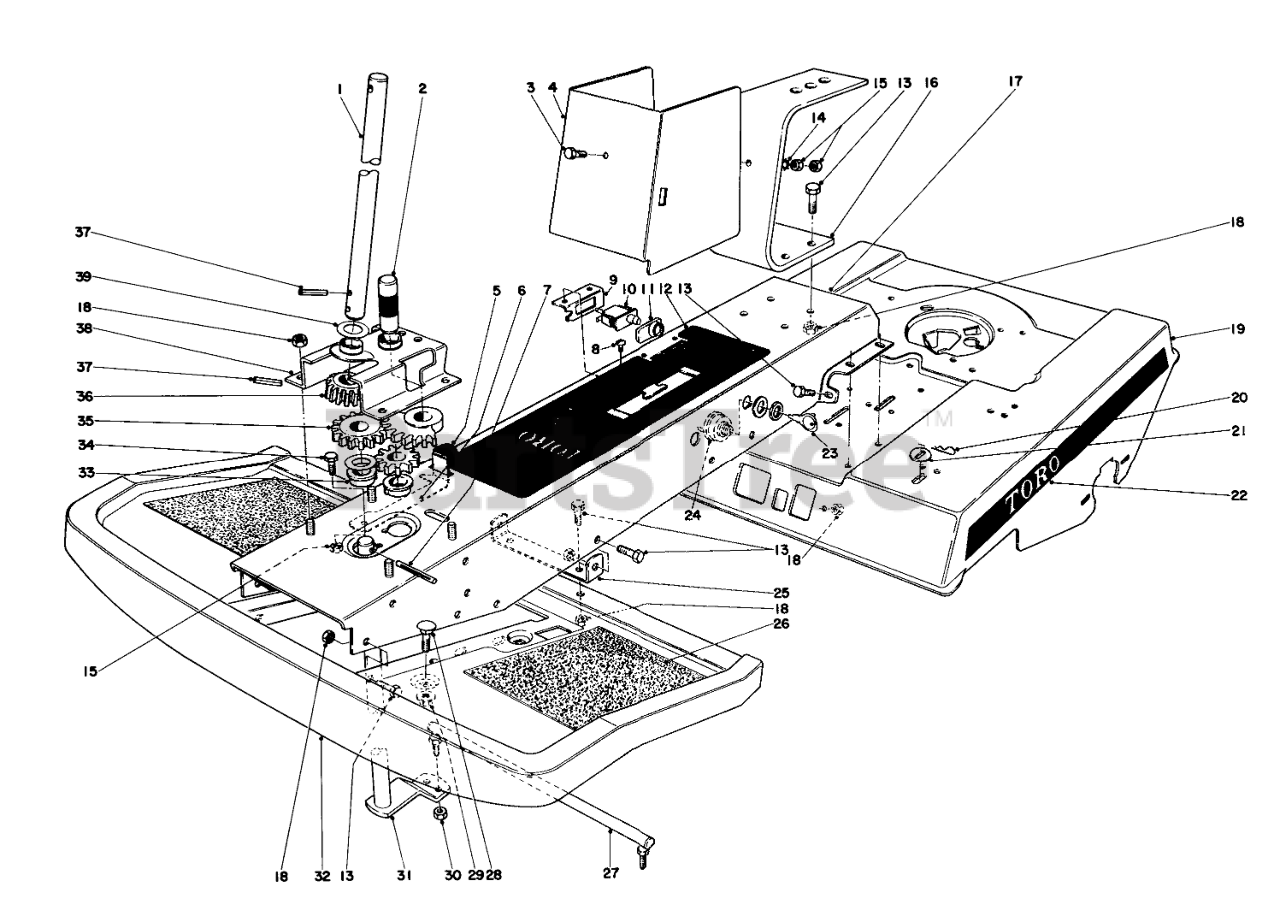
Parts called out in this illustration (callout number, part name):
1	Shaft Upper
2	Steering Idler Ass-y.
3	SCREW-HH
4	Cover Seat
5	Parking Brake Tip
6	Parking Brake Spring
7	3/16 X 1-1/2 GRVE PIN
8	SCREW-HWHTF
9	Switch Bracket
10	Switch
11	Boot Switch
12	Throttle Control Decal
13	SCREW-HH
14	WASHER-LOCK/EXT
15	NUT-LOCK, CONE
16	Seat Spring
17	Center Frame Member
18	NUT-LOCK, CONE
19	Engine Mounting Frame
20	PIN-COTTER
21	Washer
22	Decal L.H.
23	Key
24	Switch
25	Support
26	Foot Tread
27	Ball Joint
28	SCREW-CARR
29	NUT-HF
30	NUT-LOCK, NI
31	Shaft
32	Foot Rest
33	Bushing
34	SCREW-HH
36	STEERING PINION
37	PIN-ROLL, SLOTTED
38	Bracket Steering Support
39	Washer
